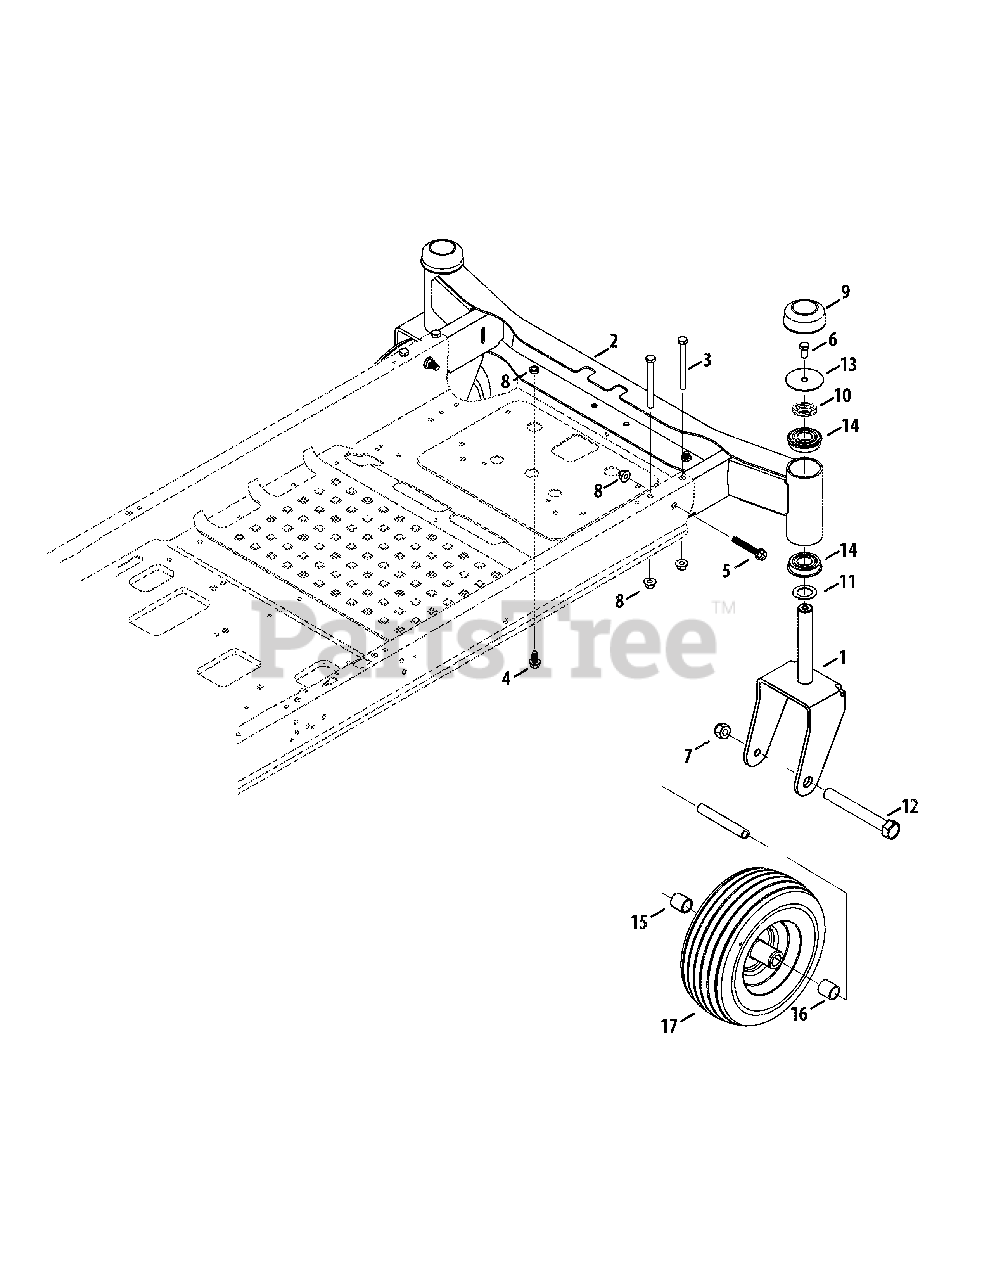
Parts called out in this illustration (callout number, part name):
1	Caster Wheel Bracket Assembly
2	Front Axle
3	Hex Screw, 3/8-16 x 1.00
4	Hex Screw, 3/8-16 x 1.00
5	Hex Flange Screw, 3/8-16 x 2.00
6	Hex Screw, 3/8-16 x .750
7	Hex Lock Nut, 1/2-13
8	Flange Lock Nut, 3/8-16
9	Shaft Cap
10	Wave Washer, .375 x 1.030 x .300
11	Thrust Washer, 1.010 x 1.560 x .060
12	Bolt, 1/2-20 x 7.25
13	Shoulder Spacer, 2.500 x .200
14	Ball Bearing 25 x 52 x 6205
15	Spacer, .51 x .75 x 5.825
16	Hub, .76 x 1.23 x .92
17	Wheel Assembly, 13 x 5-6
